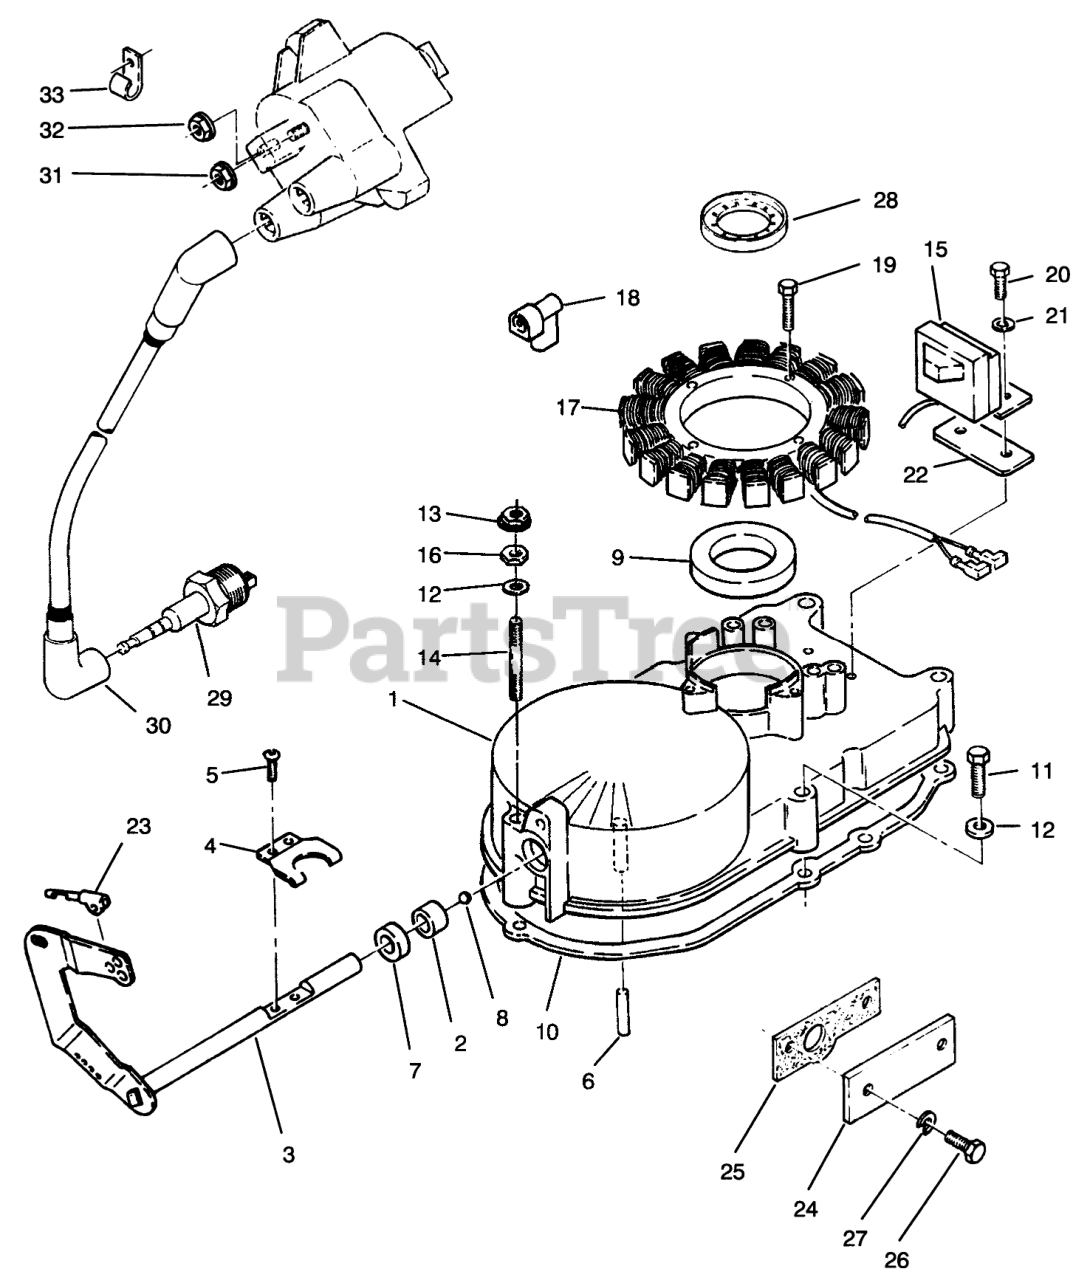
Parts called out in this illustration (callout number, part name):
1	Kit-Gearcase (Incl. Ref. #2-9)
2	BEARING
3	GOVERNOR-SHAFT & ARM
5	SCREW-PAN HD
6	Washer
10	Gasket
11	Bolt
12	WASHER
13	Nut
14	Stud
15	Control-Ignition
16	NUT-GEAR COVER
17	Stator
18	RECEPTACLE TERMINAL
19	Bolt
20	Bolt
21	Lockwasher
22	Insulator
24	Plate
25	GASKET
26	Bolt
27	Washer
28	Rotor
29	SPARK PLUG
30	Wire-Plug
31	Nut
32	Nut
33	Clip
